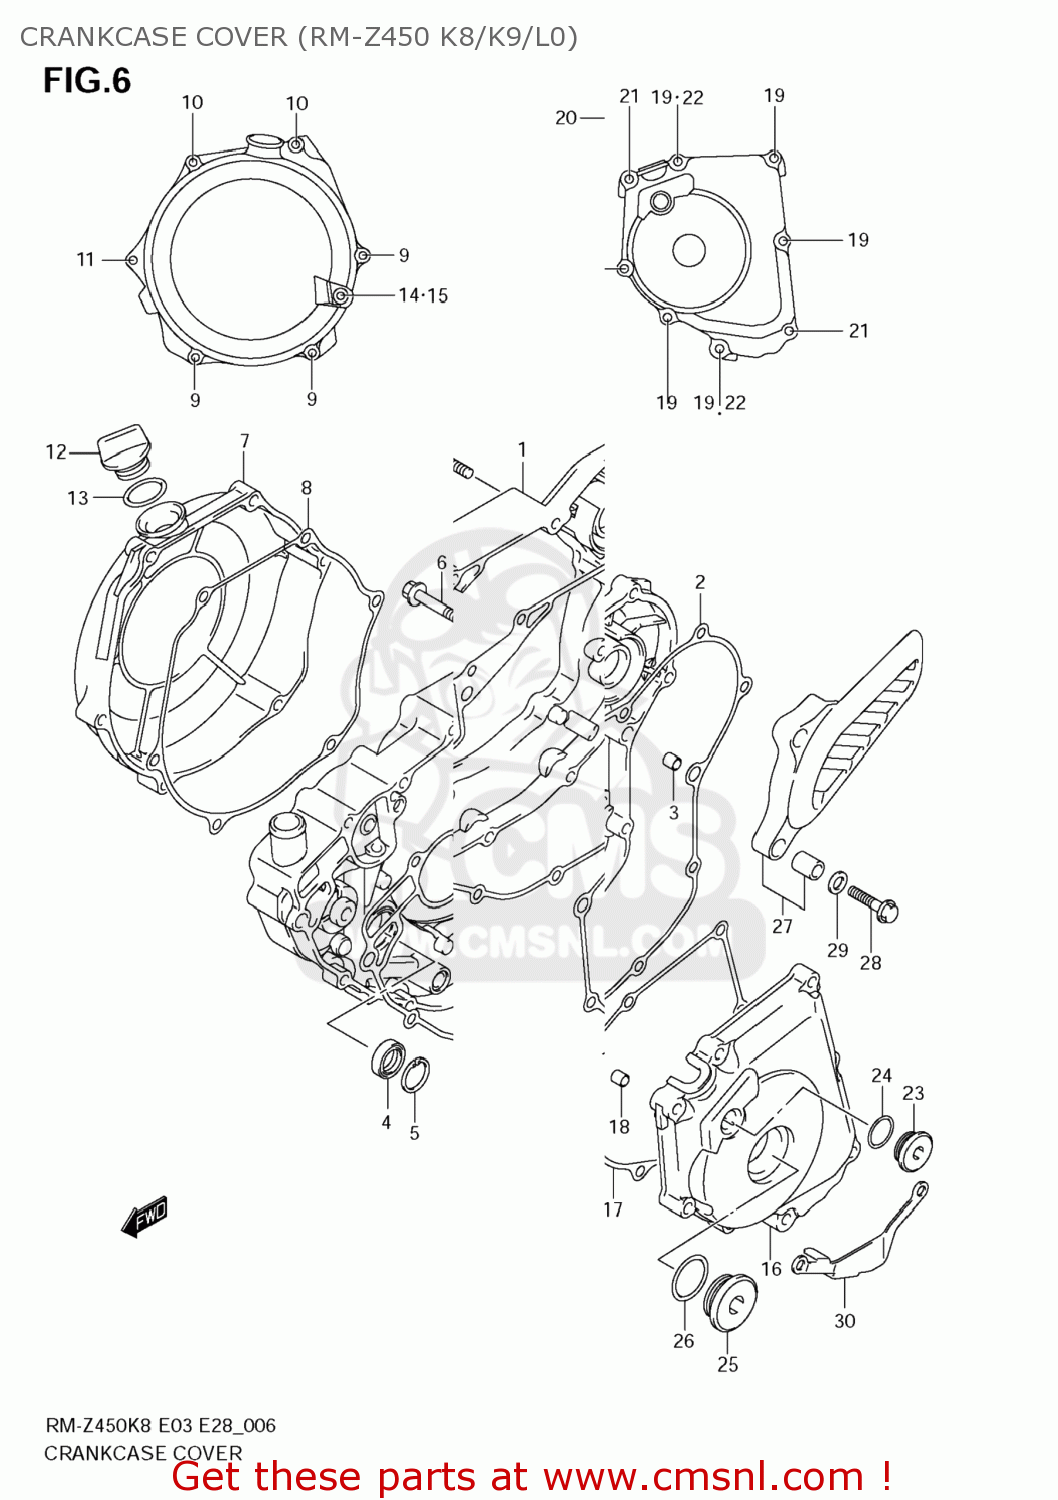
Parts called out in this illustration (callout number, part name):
1	COVER,CLUTCH
2	GASKET,CLUTCH COVER (NAS)
3	PIN
4	SEAL,OIL(12X22X6)
5	CIRCLIP
6	BOLT
7	COVER,CLUTCH OUTER
8	GASKET,CLUTCH COVER OUTER (NAS)
9	BOLT
10	BOLT
11	BOLT
12	PLUG
13	O RING(D:3.1,ID:16.8)
14	SCREW(6X10)
15	GASKET(6.2X11X1).2 (NAS)
16	COVER,MAGNETO
17	GASKET,MAGNETO COVER (NAS)
18	PIN
19	BOLT
20	BOLT
21	BOLT
22	GASKET(5.8X13X1.2) (NAS)
23	PLUG(12X9)
24	O RING(D:1.9,ID:9.8)
25	PLUG(26X9)
26	O RING(D:3.1,ID:22.7)
27	COVER,ENGINE SPROCKET
28	BOLT(6X30)
29	WASHER
30	GUARD,MAG COVER
